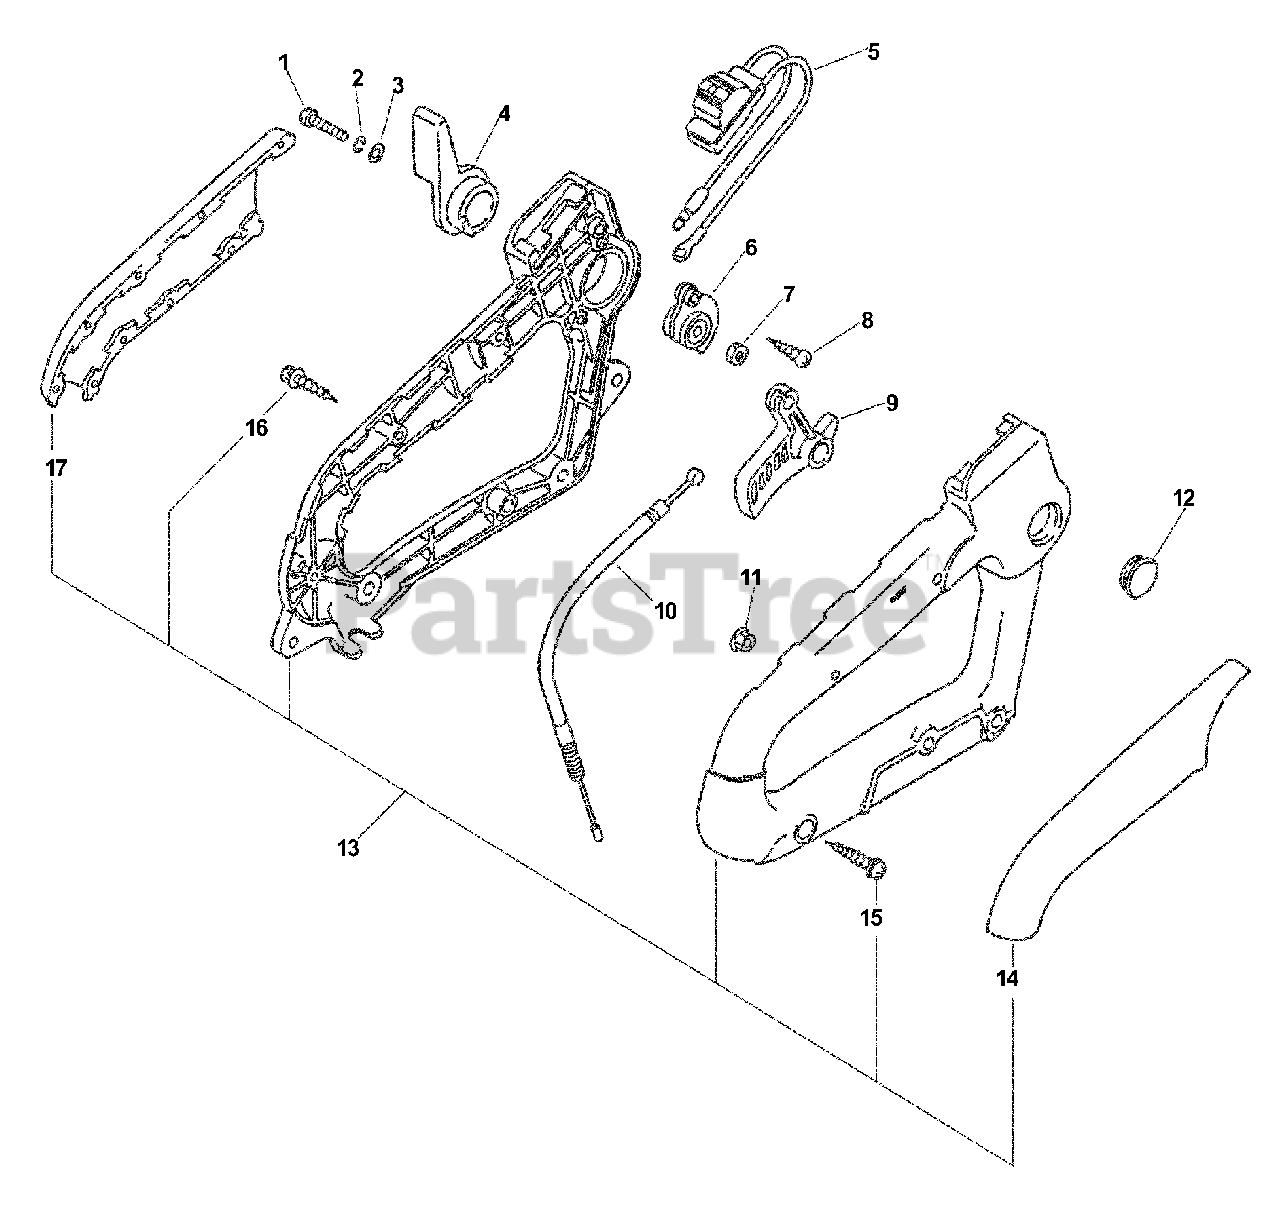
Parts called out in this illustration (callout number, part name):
1	SCREW - 6X20
2	LOCKWASHER - 6
3	WASHER - 6
4	CONTROL, THROTTLE
5	IGNITION SWITCH ASSY
6	BRACKET, THROTTLE
7	LOCKNUT - 6
8	SCREW - 4X10
9	TRIGGER, THROTTLE
10	CABLE, THROTTLE
11	NUT - 5 -- FLANGE
13	HANDLE SET - REAR
14	GRIP, HANDLE - RIGHT
15	SCREW - 5X30
16	SCREW - 4X22
17	GRIP, HANDLE - LEFT
